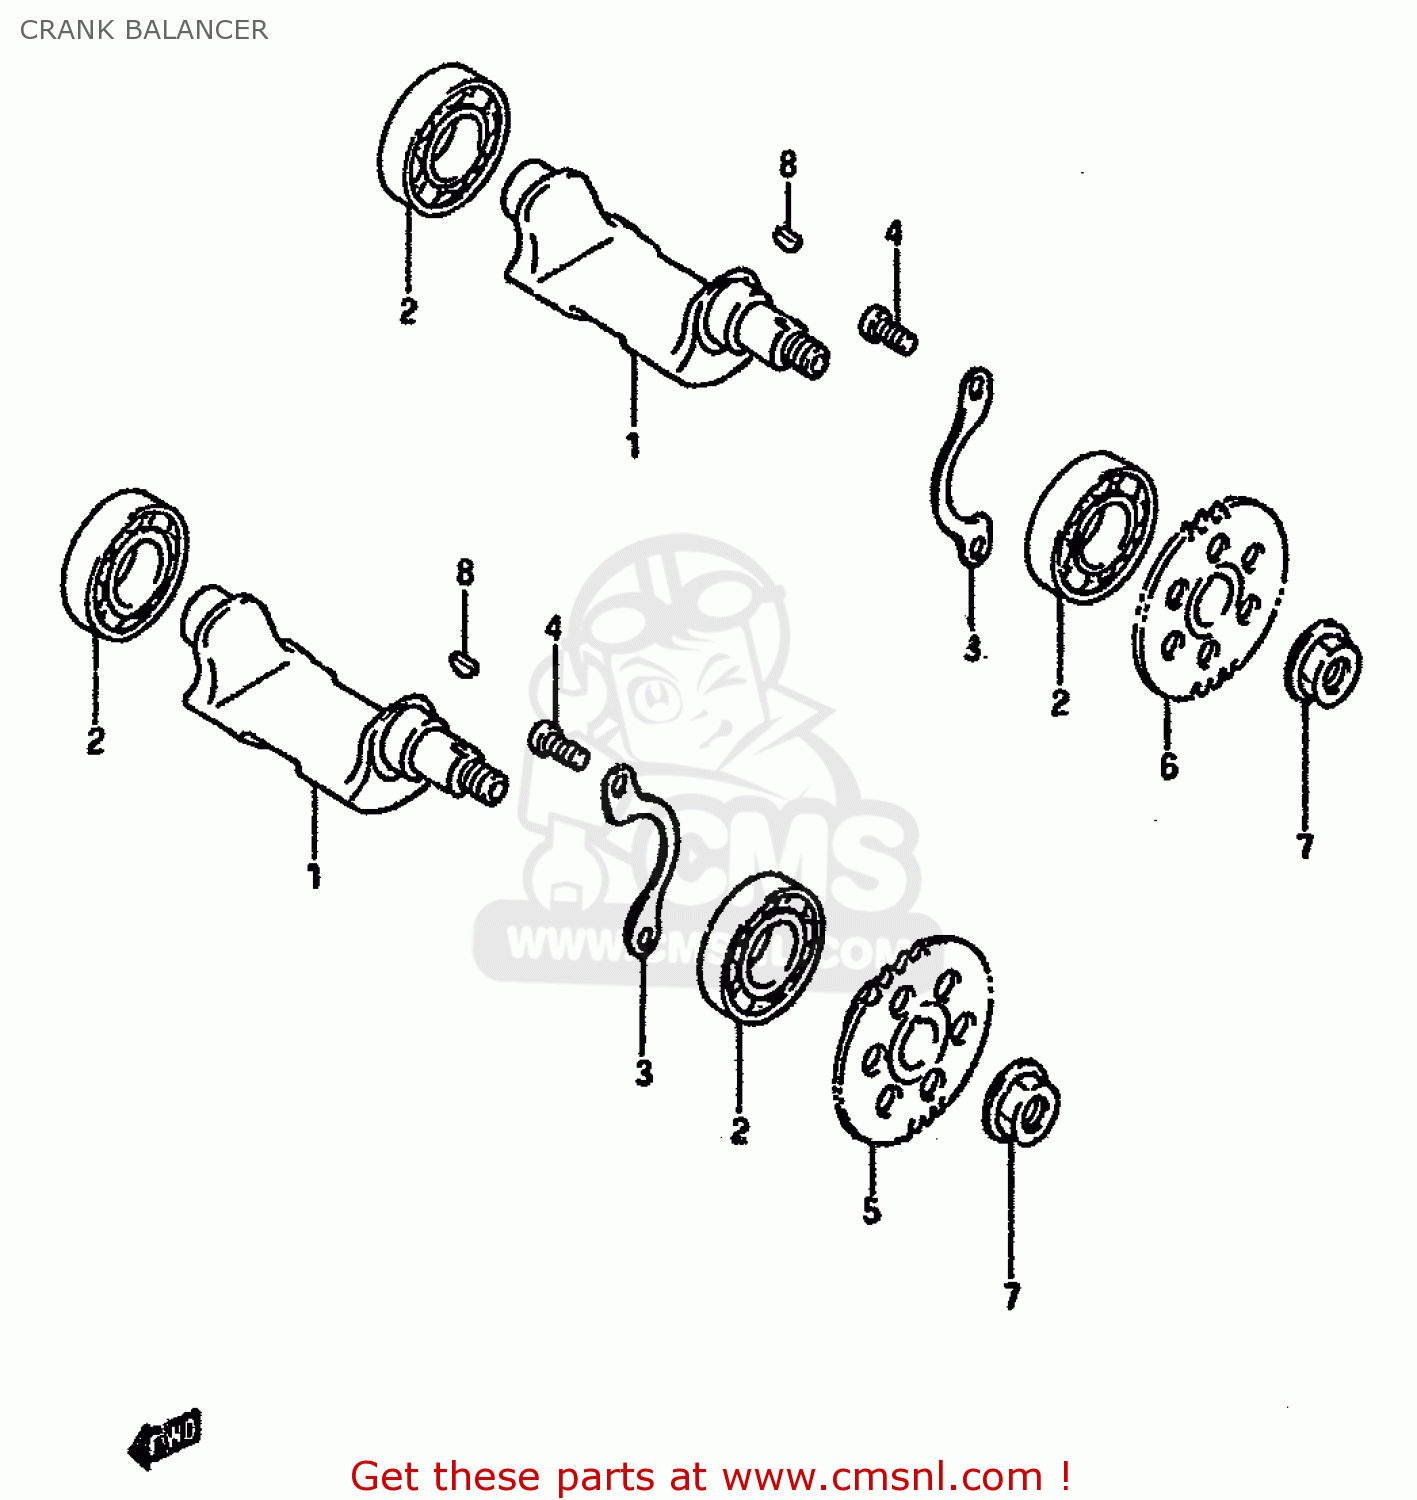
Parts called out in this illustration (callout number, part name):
1	BALANCER,CRANKSHAFT
2	BEARING
3	RETAINER,CRANK BAL BEARING
4	SCREW
5	SPROCKET,BALANCER DRIVE
6	SPROCKET,BALANCER DRIVE
7	NUT
8	KEY
